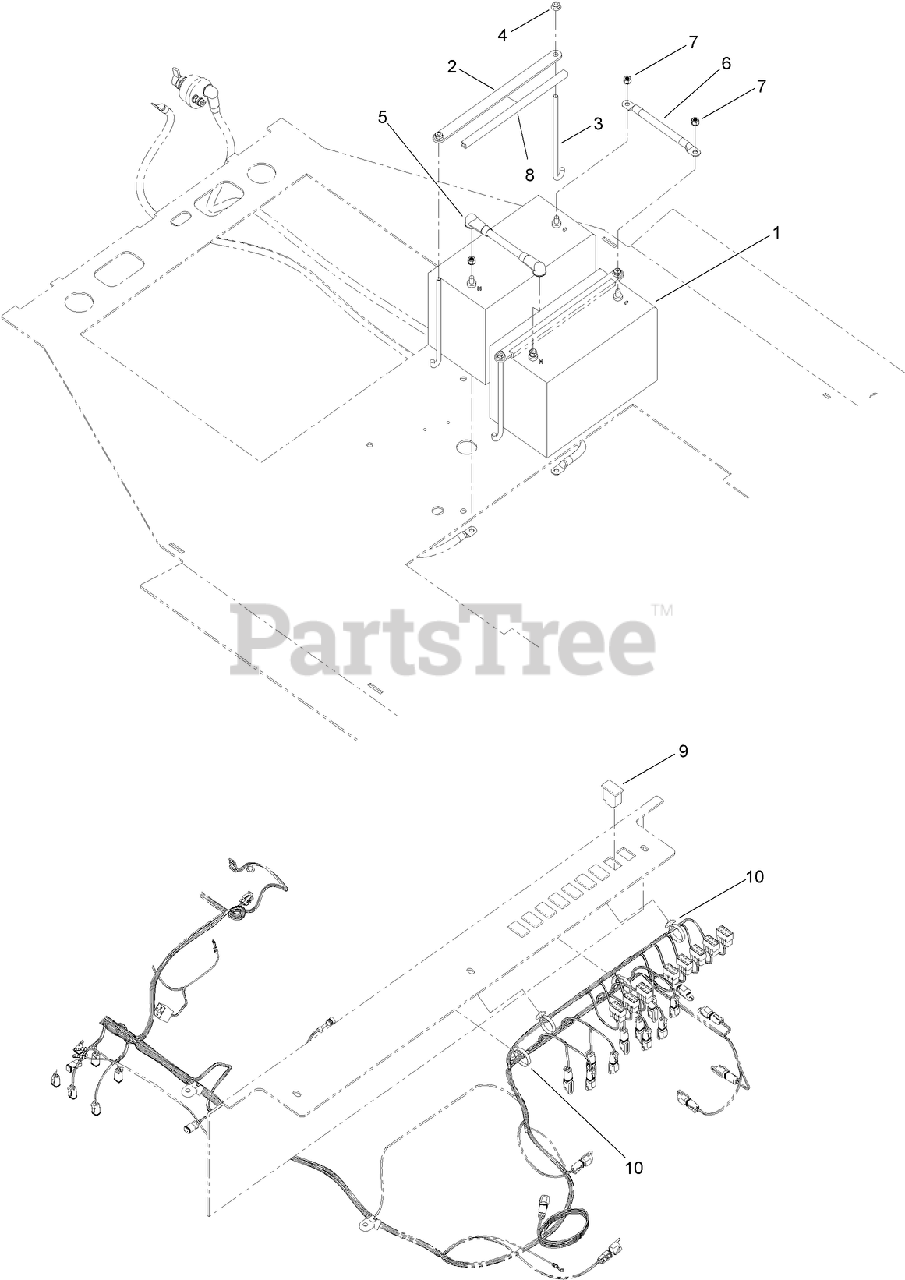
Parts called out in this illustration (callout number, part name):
1	BATTERY (950CCA, WET)
2	PLATE-HOLD DOWN, BATTERY
3	BOLT-HOLDDOWN, BATTERY
4	NUT-HF, NI
5	CABLE-BATTERY, POSITIVE
6	CABLE-BATTERY, NEGATIVE
7	NUT-KEPS
8	TRIM-BATTERY
9	PLUG-PANEL
10	TIE-BUTTON HEAD
